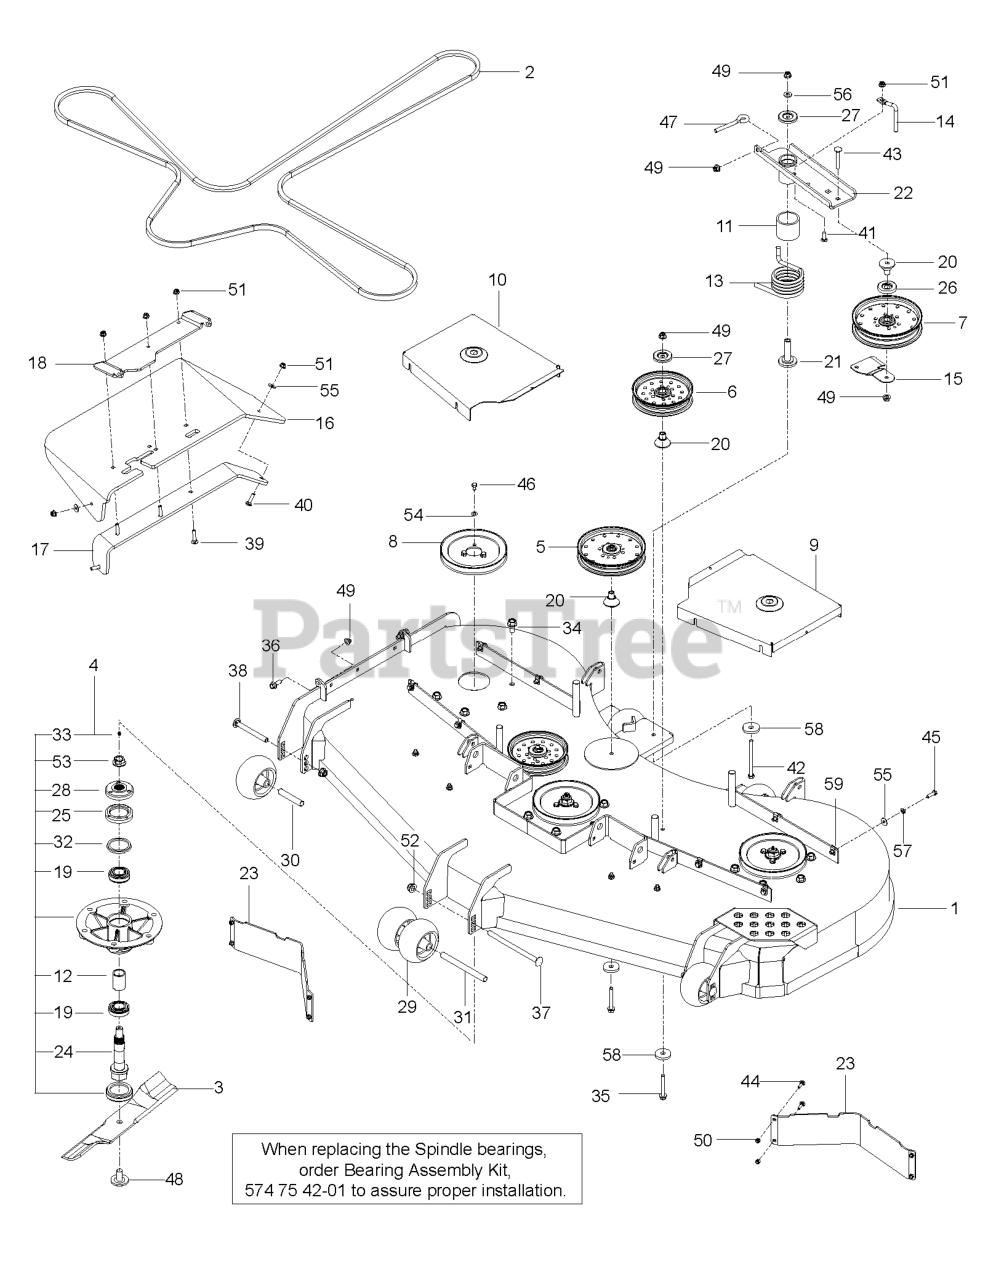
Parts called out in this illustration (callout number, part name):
1	DECK.SVC.W/DECALS.72.ORANGE.HU
2	RP.BELT, "5V", 201"
3	BLADE OEM - 25"
4	SPINDLE ASM. 10"
5	PULLEY - 7" NARROW
6	PULLEY IDLER, 6" NARROW
7	PULLEY - IDLER 7"
8	PULLEY - 7.50
9	SHIELD, BELT 72 R.H. ORANGE
10	SHIELD, BELT 72 LH ORANGE
11	SPACER, IDLER PIVOT
12	SPACER - BEARING
13	SPRING, TORSION, IDLER
14	BELT KEEPER
15	BELT.GUIDE.BLACK
16	CHUTE, DISCHARGE 60-72
17	BRKT - CHUTE SUPPORT BLACK
18	BRKT - CHUTE MTG BLACK
19	BEARING - 206KRR8
20	BEARING, IDLER ARM
21	BEARING, IDLER PIVOT
22	ASSY, IDLER ARM, PZ
23	BAFFLE, DIVERTER 72" BLACK
24	SHAFT - SPINDLE
25	CUP - DEBRIS
26	SHIELD, DUST
27	DUST SHIELD
28	HUB - PULLEY
29	ROLLER, GAUGE .635 BORN
30	TUBE, ROLLER AXLE
31	TUBE, ROLLER AXLE LONG
32	V-RING, 55MM
33	ZERK
34	HHFS 1/2-13 X 1 GR5 ZD
35	HHFS 3/8-16 X 2 3/4
36	HHFS 3/8-16 X 1 GRD 5 ZD
37	RHSNB 1/2-13 X 8 GR5 ZD
38	RHSNB 1/2-13 X 4.75 GR5 ZD
39	RHSNB 5/16-18 X 1-1/2 GR 5 ZD
40	BOLT, CARRIAGE 5/16X1-1/4
41	RHSSNB 5/16C X 1.0
42	HCS 3/8-16 X 4-1/2 GR 8 ZD
43	CARRIAGE BOLT 3/8-16 X
44	1/4-20X3/4 CARR BLT
45	HCS 5/16C X 1
46	HCS 5/16-18 X 1/2 GR 5 ZD
47	EYE BOLT, 3/8 X 4"
48	BLADE BOLT/WASHER
49	NUT 3/8-16 HEX FLG NYLOC ZD
50	NUT.1/4-20.HEX.NYLOC.ZD
51	5/16-18 NYLOC FLANGE NUT
52	NUT, 1/2-13 HEX FLG NYLOC ZD
53	NUT FLANGE 3/4-16
54	WASH 5/16 DISC SPRING ZD
55	WASHER 5/16 FLAT
56	WASHER, 3/8 THICK
57	WASHER.LOCK.HVY.HLCL.SPR.5/16
58	SPINDLE WASHER
59	U-CLIP 5/16-18 NUT RETAINER
